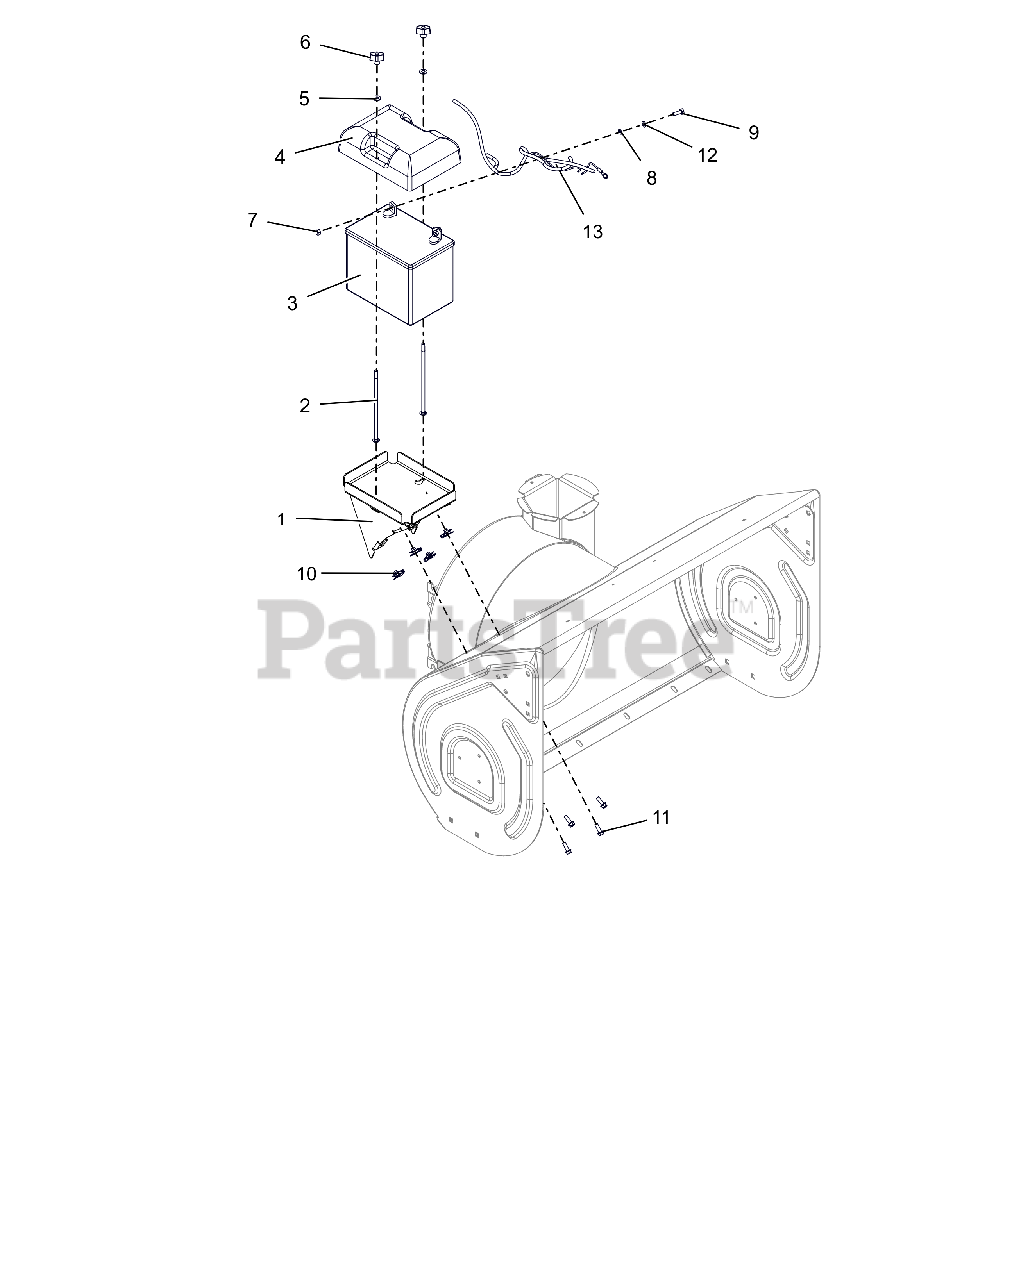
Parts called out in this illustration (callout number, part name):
1	TRAY, BATTERY
2	@BLT-RDHDSQNK .25-20X7.00 G2YZ
3	BATTERY, 300 CCA 10U1L
4	COVER, BATTERY
5	@WSHR-FL-STL.281X.62X.065 YWZC
6	KNOB, WING - .25-20 UNC
7	@NUT-HEX .25-20 YWZC
8	@WSHR-LK .25X.062 REG YWZC
9	@BLT-HEX .25-20X.75 GR5 YWZC
10	NUT-RTNR .25-20X.56
11	BLT-HEX .25-20X.75 HWH YZ GR5
12	WSHR-FL-STL .265X.50X.087YWZC
13	HARNESS, ELEC - 12V BRIGGS
